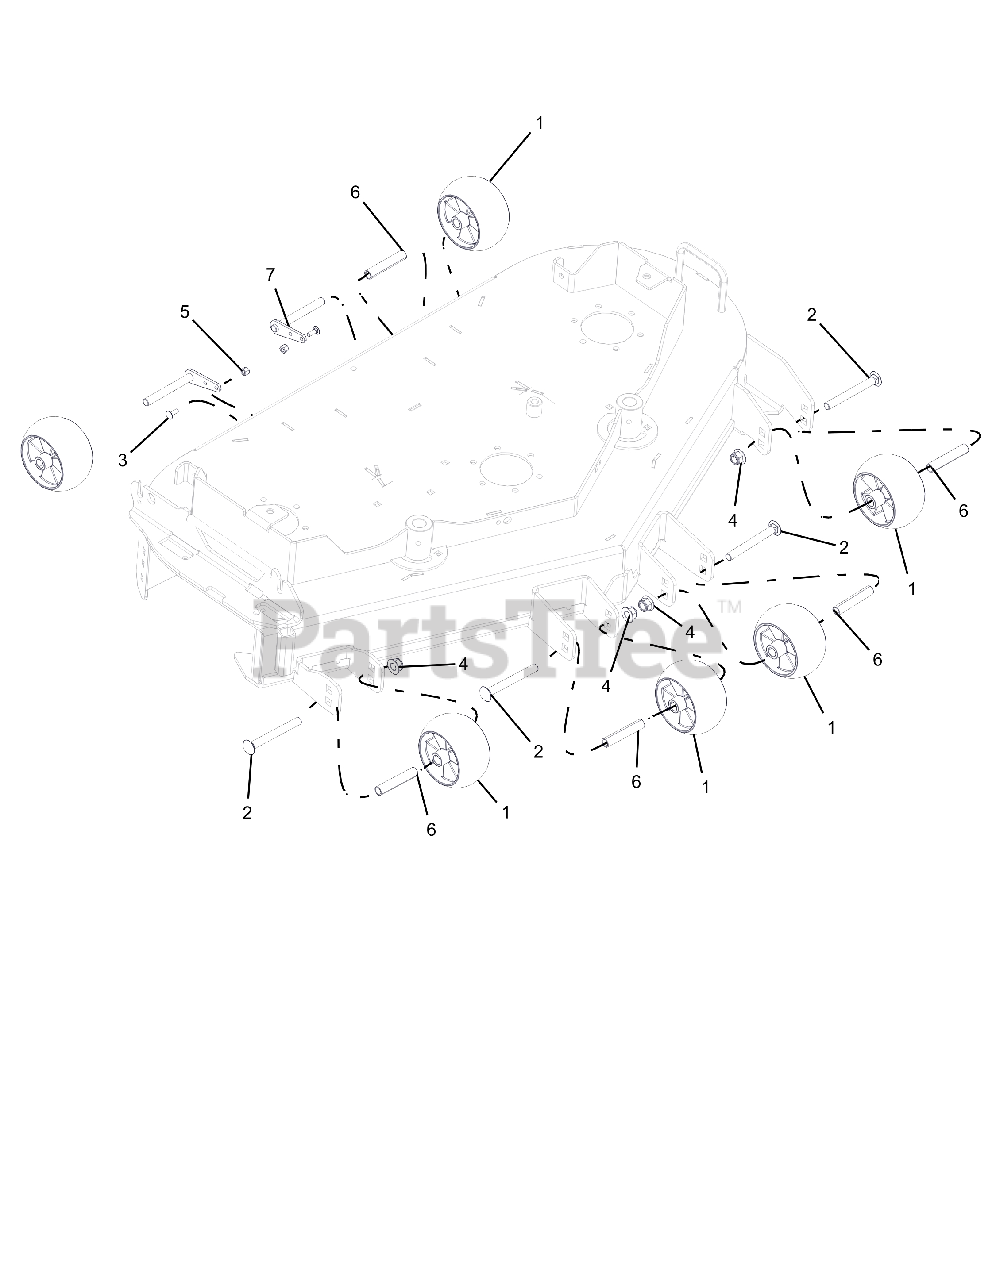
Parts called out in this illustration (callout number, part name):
1	ANTI-SCALP WHEEL - 5X3 CTR
2	BLT-RDHDSQNK .50-13X4.50 G5 YWZC
3	BLT-RDHDSQNK .25-20X.75 G5 YWZC
4	NUT-LK-NYL-FLG .50-13 YWZC
5	NUT-LK-NYL .250-20 YWZC
6	SPACER, .510X.625X3.35
7	PIVOT, RETAINING WELD
